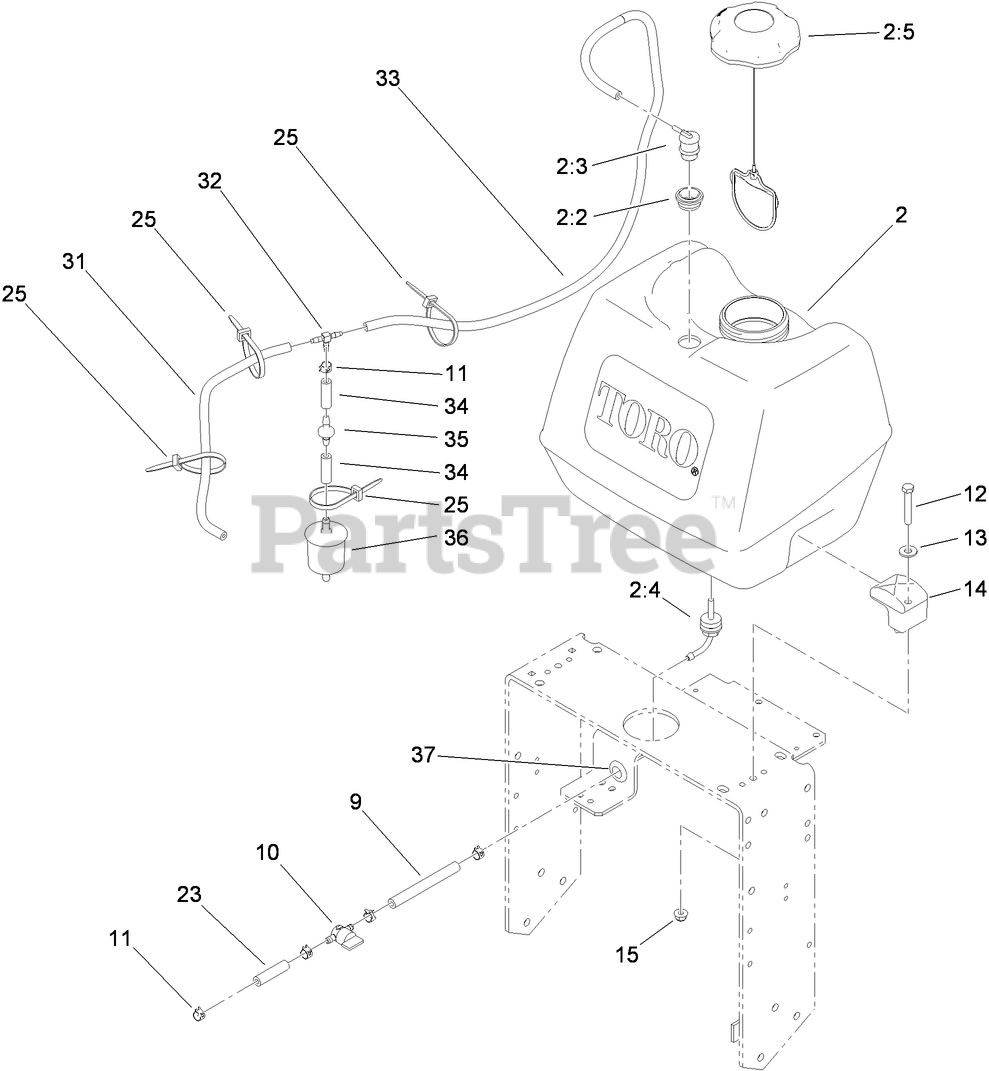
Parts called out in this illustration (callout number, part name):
2	FUEL TANK ASM
2:2	GROMMET-VALVE, ROLL-OVER
2:3	VALVE-ROLLOVER
2:4	FITTING-FUEL, BULKHEAD
2:5	CAP-FUEL, RATCHETING
9	HOSE-FUEL
10	VALVE-FUEL
11	CLAMP-HOSE
12	SCREW-HH
13	WASHER-FLAT
15	NUT-HF, NI
23	HOSE-FUEL
25	TIE-CABLE
31	HOSE-FUEL
32	FITTING-TEE
33	HOSE-EMISSIONS
34	HOSE-FUEL
35	VALVE-CHECK, FUEL
36	FILTER-FUEL
37	GROMMET
